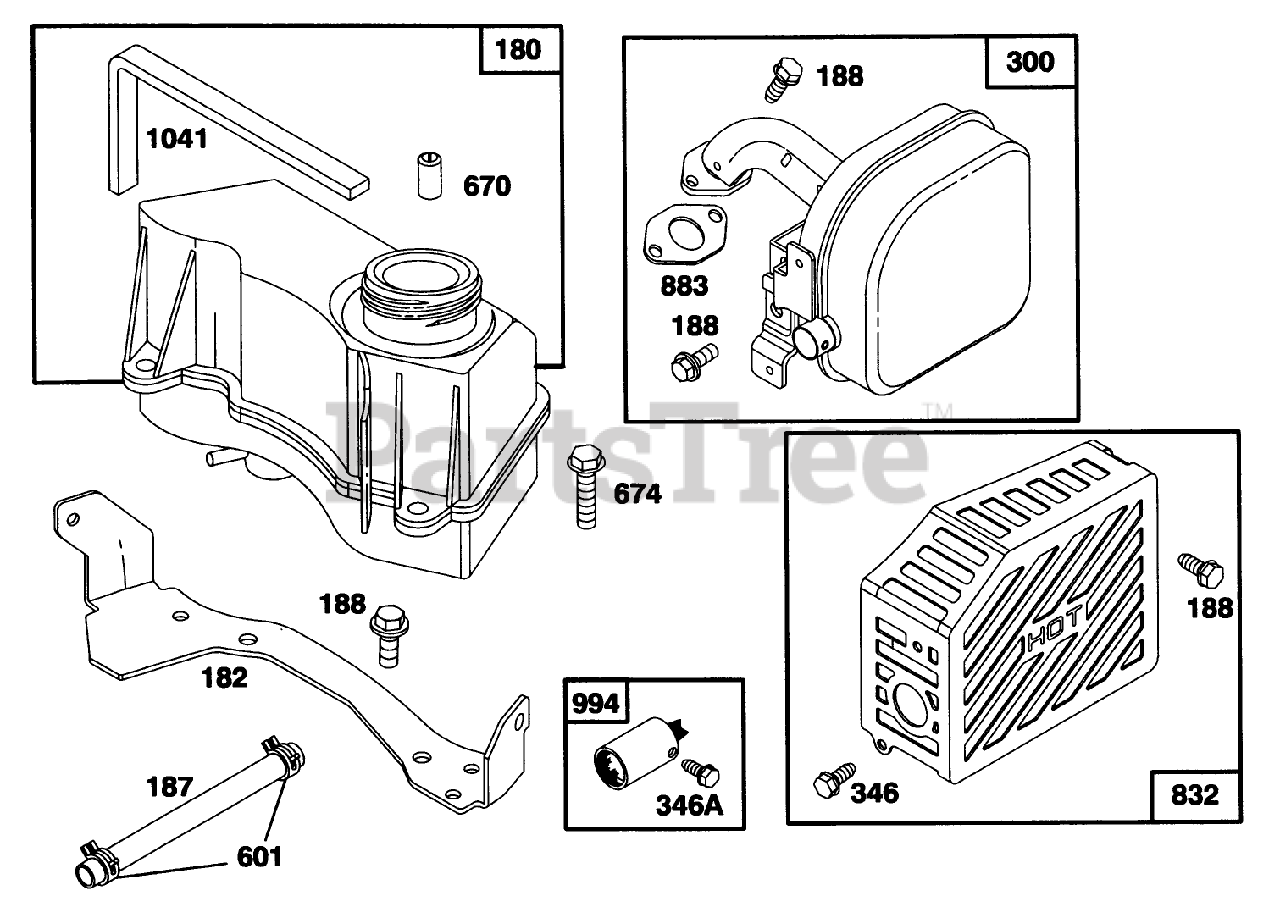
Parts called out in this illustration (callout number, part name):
180	TANK ASSY - FUEL
188	SCREW - SEM
300	MUFFLER - EXHAUST
346	SCREW - SELF-TAPPING
601	CLAMP - CL PIPE
670	SPACER
674	SCREW - HEX HEAD
